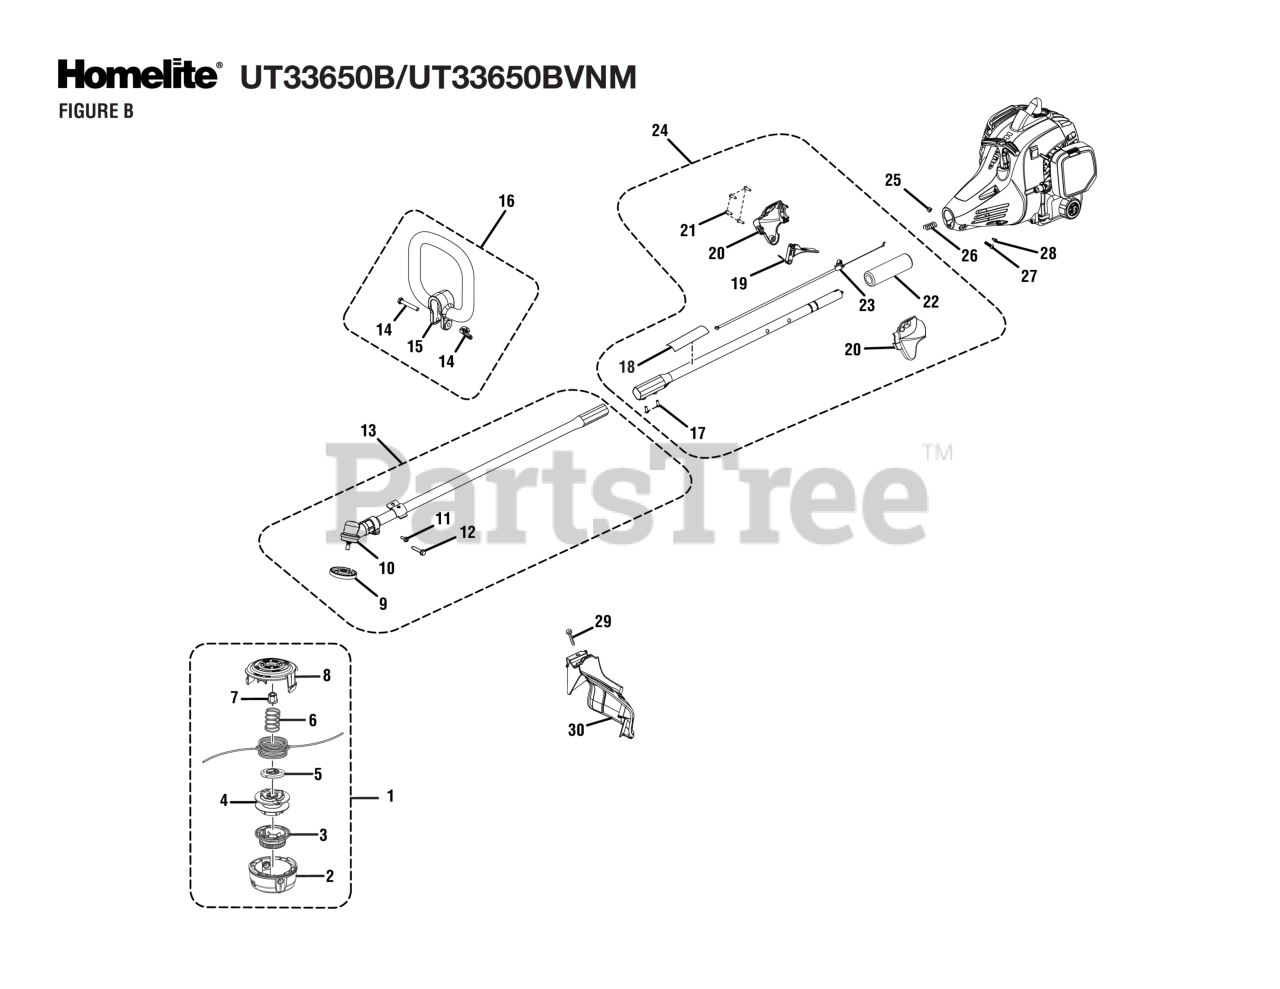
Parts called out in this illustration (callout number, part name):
1	Trimmer Head Assembly
2	Lower Housing
3	Bump Knob (Gray)
4	Spool Assembly
5	String Guide
6	Compression Spring
7	Hex Nut (M8, Left Hand Threads)
8	Upper Housing
9	FLANGED WASHER
10	Gear Case Assembly
11	Screw w/Washer (10-24 x 5/8 in., Hex Hd. T.F.)
12	Screw (1/4-20 x 1-1/4 in., Hex Washer Hd. S.T.)
13	Lower Boom Assembly
14	Fastener Parts Kit
15	Front Handle
16	Front Handle Assembly
17	Set Screw (M5 x 10 mm, Hex Soc. Hd.)
18	Icon Warning Label
19	Throttle Trigger
20	Trigger Handle Assembly
21	Screw (M4 x 20 mm, T20 Torx Pan Hd. T.Fl.)
22	Rubber Grip
23	Throttle Cable
24	Boom Assembly
25	Hex Nut (M6.3 x 1)
26	Compression Spring
27	Screw (M6 x 20 mm, T27 Torx Button Hd.)
28	Screw (M4 x 8 mm, T25 Torx Pan Hd. T.F.)
29	SCREW (#1/4-20 X 1-1/4 in. HEX WASHER HD.)
30	Grass Deflector Assembly
